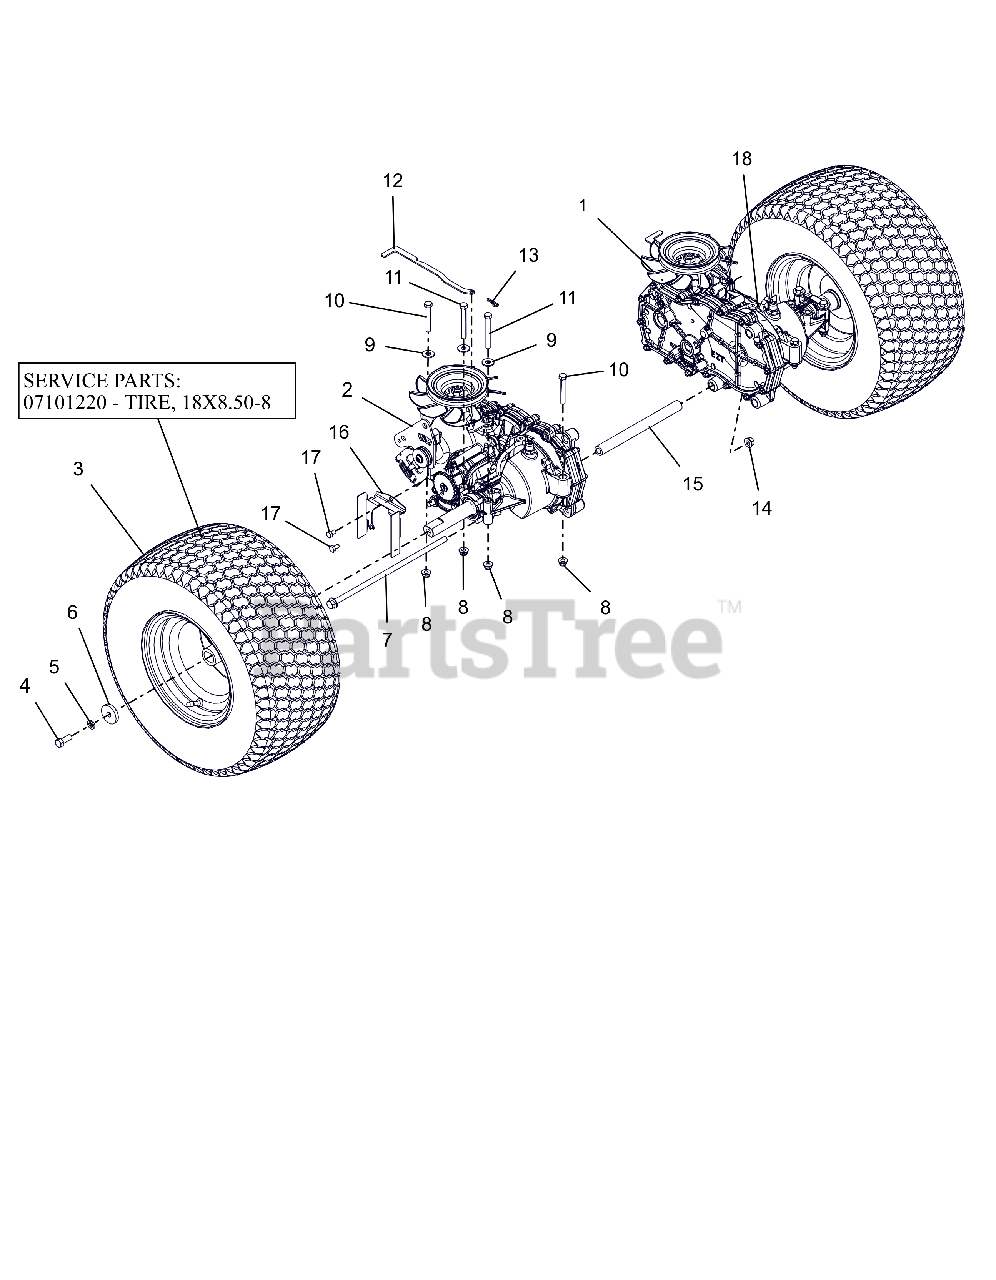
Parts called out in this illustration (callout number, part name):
1	TRANSAXLE EZT D-SHFT SHORT
2	TRANSAXLE EZT D-SHFT SHORT
3	ASM, WHL/TIRE 18X8.50-8 DHUB
3	TIRE, 18X8.50-8
4	BLT, HEX .38-16X1.00 G8ZCCEP30
5	WSHR,LK-REG .375X.094 ZCC
6	WSHR, FLT .406X1.50X.245 ZCC
7	BLT,HEX-FLG .38-16X11.5 G5 ZCC
8	NUT,LK-NYL-FLG .31-18 G5ZC120
9	WSHR,FLT .375X.875X.083 ZCC
10	BLT, HEX .31-18X2.25 G5 ZCC
11	BLT, HEX .31-18X2.75 G5 ZCC
12	BRKT, DUMP VALVE
13	PIN, HAIR #213 .08X1.19 ZCC
14	NUT-LK-CTR-FLG .375-16 GF ZCC
15	TUBE, TRANSAXLE BRACE 8.18LG
16	GUARD, PARKING ,BREAK RH (GREY PEARL)
17	BLT,HEX .25-20X.50 G5 ZCC
18	GUARD, PARKING BRAKE LH (GREY PEARL)
